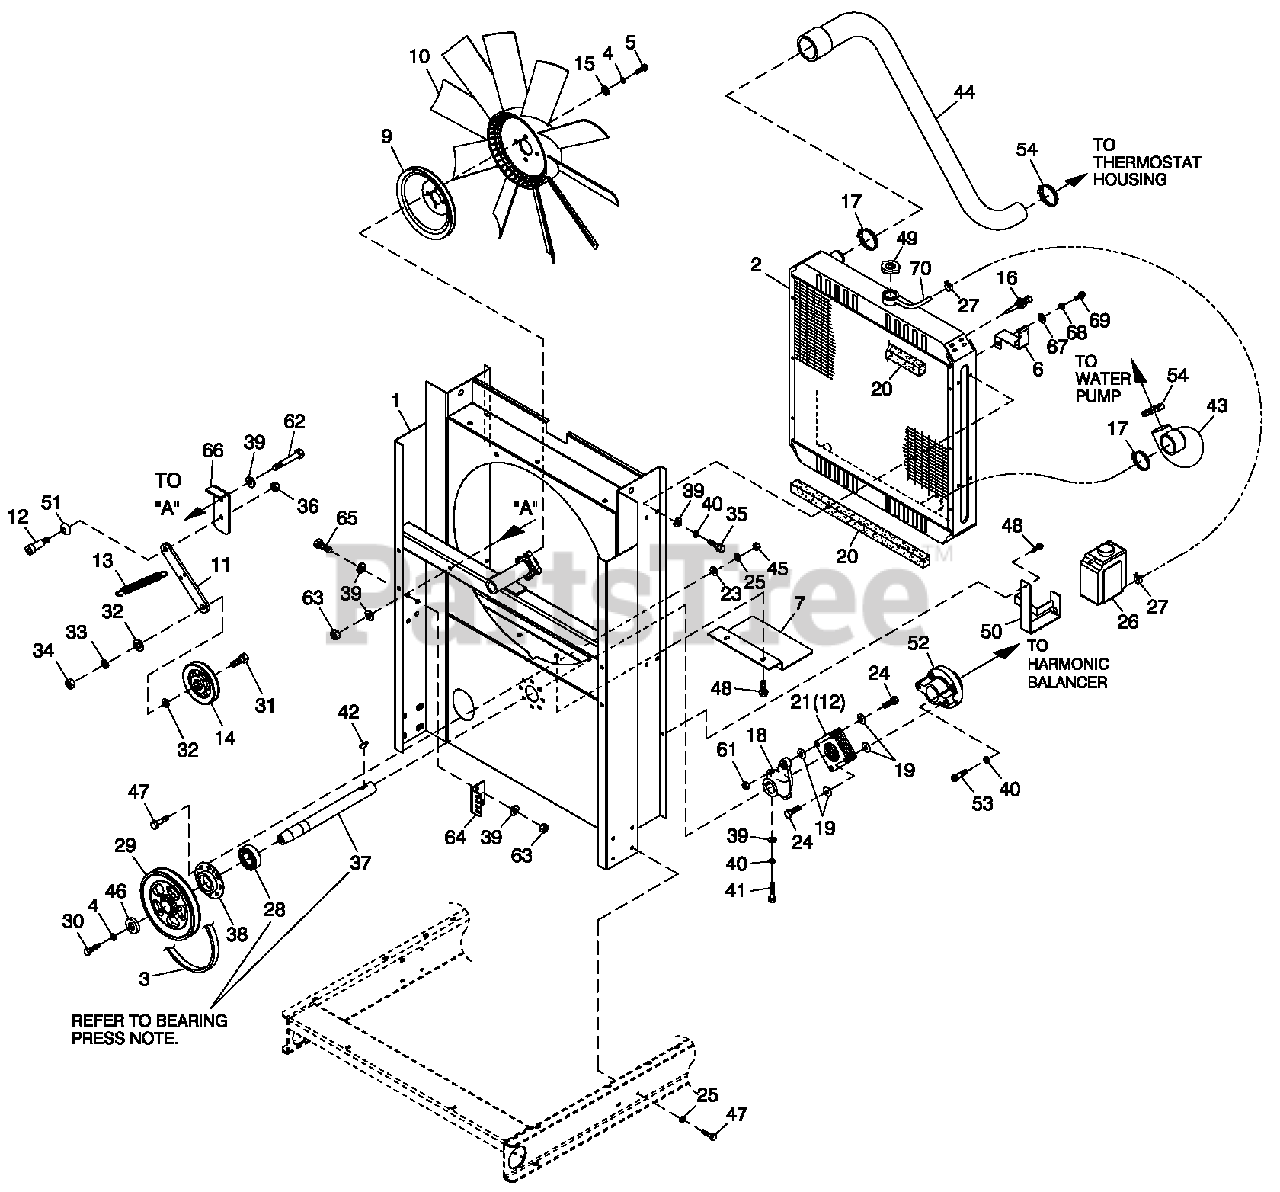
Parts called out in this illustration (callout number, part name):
1	WELDMENT RADIATOR SUPPORT C2
2	RADIATOR 598 X 568 X 49,CPL LH
3	V-BELT A58 (60IN O.C.) DDC S60
4	WASHER LOCK M10
5	SCREW HHC M10 -1.5X 30 G10.9
6	BRACKET, SIGNAL CONDITIONER (USED ONLY WITH QTA PRODUCT)
7	SHIELD RADIATOR C4
9	PULLEY FAN V-GROOVE 9"
10	FAN COOL 22" D IA 10 BLADE LH
11	FLAT TENSIONER ARM
12	SHOULDER BOLT 3/8 X 1/2"
13	SPRING TENSION CPL
14	PULLEY V -BELT 4" FLANGED
15	WASHER FLAT 3/8-M10 ZINC
16	PROBE COOLANT LEVEL 3/8 NPTF
17	CLAMP HOSE #28 1.32-2.25
18	HUB FLEX PLATE
19	WASHER FLEX (THIN)
20	TAPE FOAM 1 X 1 (26.75" LG)
21	DISK FLEX
23	WASHER FLAT 1/4-M6 ZINC
24	SCREW HHC 5/16-24X1.124
25	WASHER LOCK M6-1/4
26	TANK COOLANT RECOVERY
27	CLAMP HOSE BAND 1/4
28	BEARING #6205 2NSE C3 E SRI2 S
29	PULLEY 6.5" DIA MACHINED
30	SCREW HHC M10-1.5X 30 G8.8
31	SCREW HHC 1/2-13 X 2" G8
32	WASHER FLAT 1/2 ZINC
33	WASHER LOCK 1/2
34	NUT HEX 1/2-13 STEEL
35	SCREW HHFC M8-1.25 X 20 W/M6
36	NUT HEX LOCK 5/16-18 NY INS SS
37	SHAFT FAN DRIVE
38	RETAINER BEARING
39	WASHER FLAT 5/16-M8 ZINC
40	WASHER LOCK M8-5/16
41	SCREW HHC M8-1.25X 35 G8.8
42	KEY WOODRUFF 4X19D
43	HOSE RADIATOR LOWER FRONT
44	HOSE RADIATOR UPPER FRONT
45	NUT HEX M6X 1.0 G8YEL CHR
46	SPACER .5 X 1.5 X .25 STL/ZINC
47	SCREW HHFC M6-1.0X 20 G8.8
48	SCREW THF M6-1 X 16 N WAZ/JS
49	CAP RADIATOR 13 PSI
50	BRACKET COOLANT TANK
51	WASHER BELLEVILLE .75X.38X.028
52	COUPLING FLEX HUB MACHINED
53	SCREW SHC M8-1.25X 30 G12.9
54	CLAMP HOSE #24 B1.06 -2.00
61	NUT HEX LOCK 5/16-24 NY INS
62	SCREW HHC M8-1.25X 75 C8.8
63	NUT HEX LOCK M8-1.25 NY INS
64	BRACKET TENSIONER SPRING
65	SCREW HHC M8-1.25X 20 C8.8
66	TENSIONER ARM SUPPORT BENT 90
67	WASHER FLAT 5/16-M8 ZINC (USED ONLY WITH QTA PRODUCT)
68	WASHER LOCK M8 -5/16 (USED ONLY WITH QTA PRODUCT)
69	SCREW HHFC M8-1.25X20 W/M6 (USED ONLY WITH QTA PRODUCT)
70	HOSE 9/32 ID (60" LG)
